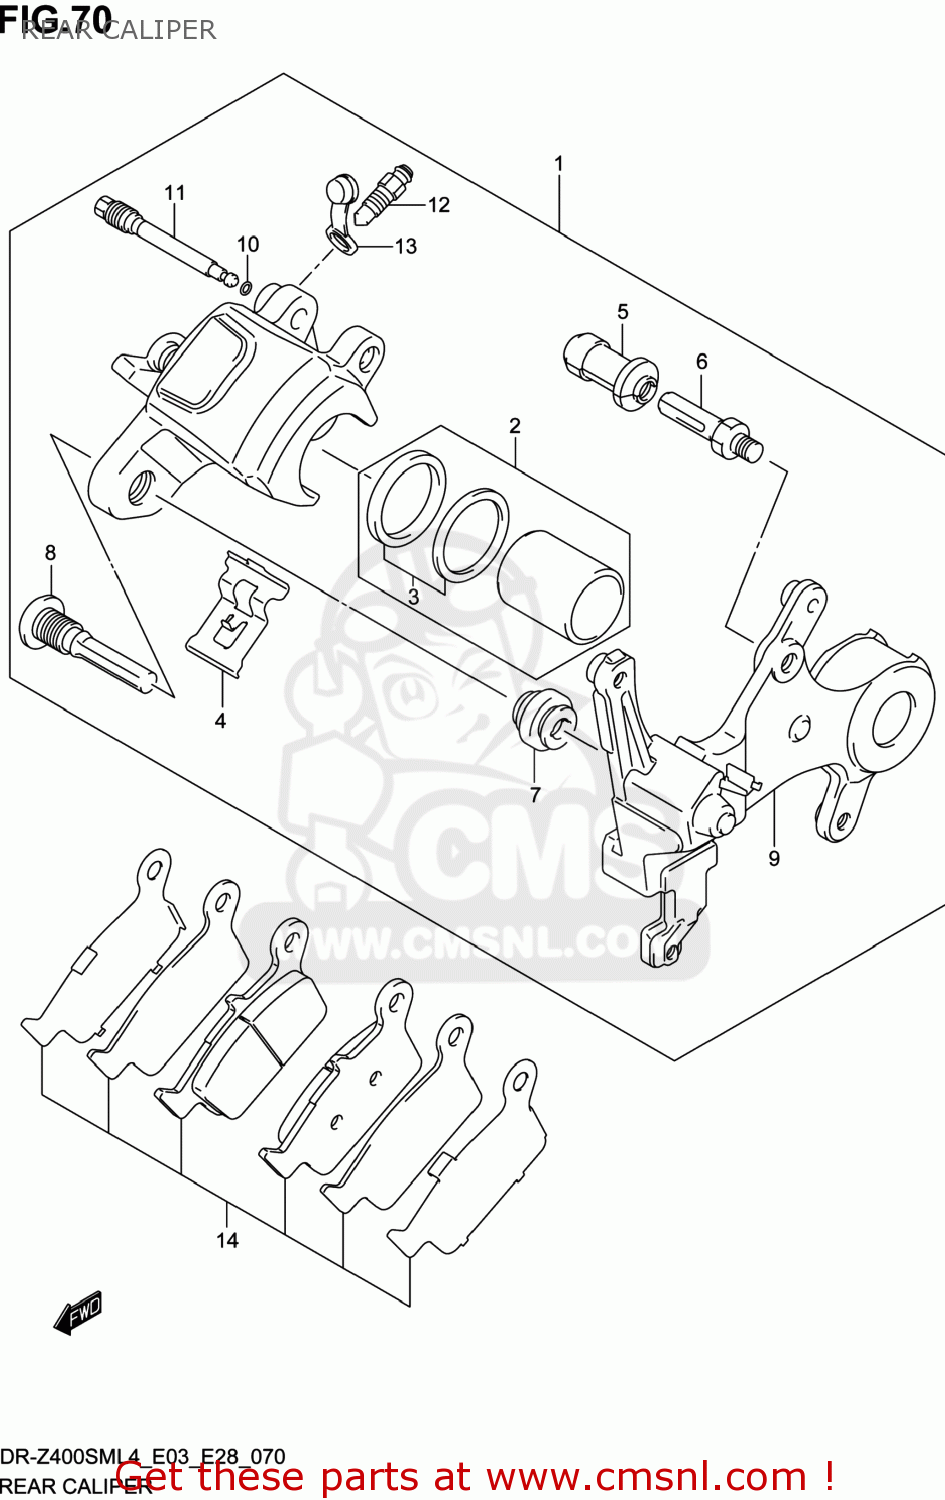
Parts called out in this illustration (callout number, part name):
1	CALIPER ASSY,RR
2	PISTON SET
3	SEAL SET,PISTON
4	SPRING,PAD
5	BOOT
6	BOLT
7	BOOT
8	PIN,BOLT
9	BRACKET
10	RING,STOPPER
11	PIN,HANGER
12	BLEEDER
13	CAP,BLEEDER
14	PAD & RETAINER SET
